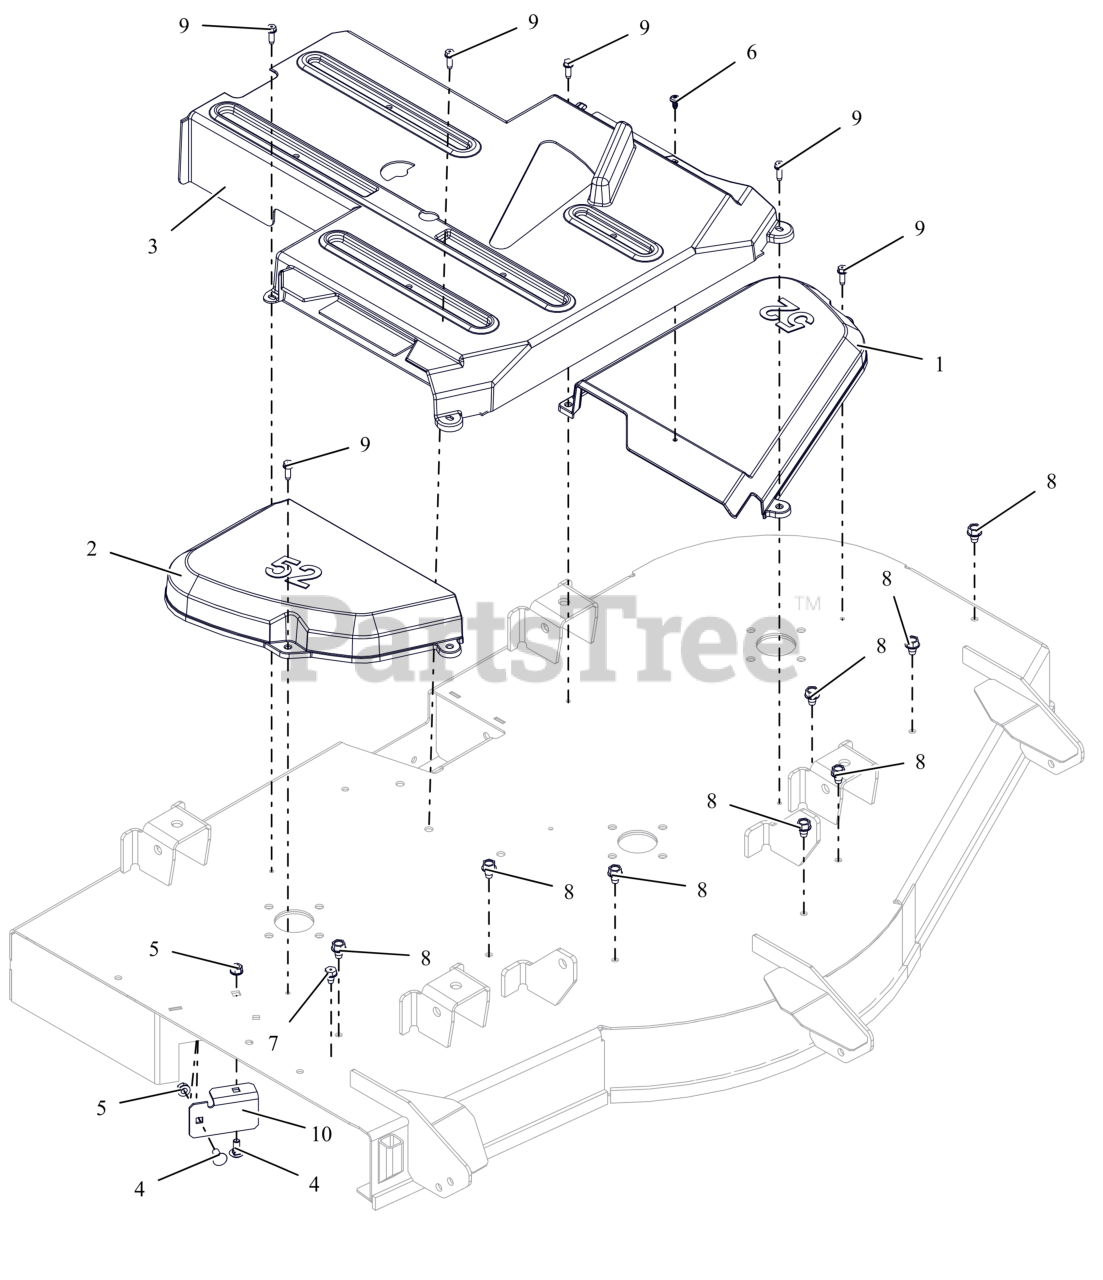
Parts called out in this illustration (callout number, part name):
1	COVER, BELT 52" LH
2	COVER, BELT 52" RIGHT
3	GUARD, CENTER, DECK
4	BLT,RHSN .31-18X.75 G5 ZCC
5	NUT-LK-TOP-FLG .312-18 GF ZCC
6	SCR-PAN .25-15X.50 6L H/LZB500
7	SCR,TAP .312-18X.50 HWH TR ZCC
8	SCR,TAP .375-16X.50 HWH TR ZCC
9	SCR,TAP .25-20X.75 HWH TR ZCC
10	STRIP, DEFLECTOR 52" (ORANGE)
